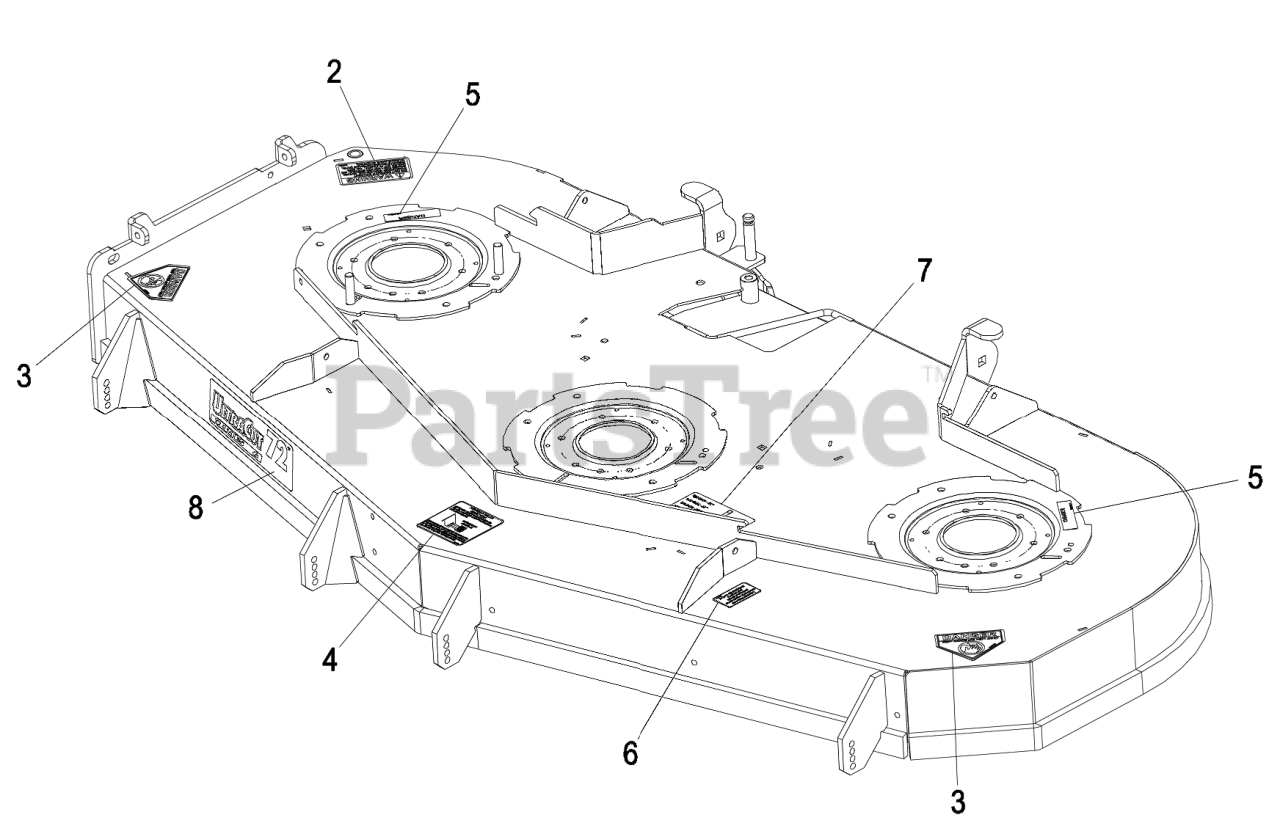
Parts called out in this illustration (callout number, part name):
2	DECAL-WARNING, DISCHARGE
3	DECAL-DANGER
4	DECAL,ANTISCALP
5	DECAL-COVER, MISSING
6	DECAL,BOLT TORQUE
7	DECAL,BELT ROUTING
8	DECAL,ULTRACUT 72 SERIES
